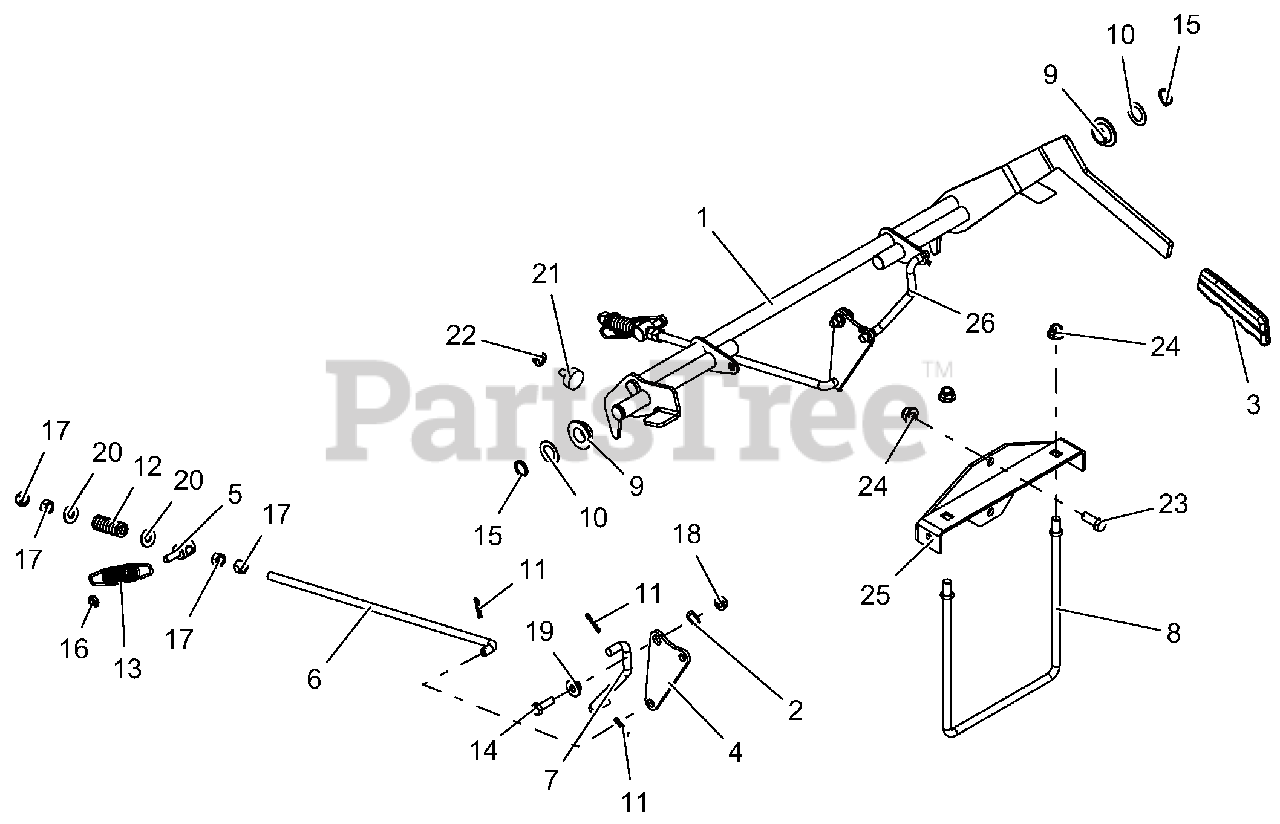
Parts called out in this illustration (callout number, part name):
1	WLDMT, PARKING BRAKE LEVER
2	WAVE WASHER .531X.781X.125 FH
3	GRIP, PARKING BRAKE (YELLOW)
4	PLATE, BRAKE PIVOT-BLACK
5	TRUNNION, .31-18
6	ROD, BRAKE ADJ.
7	LINKAGE, RH BRAKE ACTUATING
8	ROD, BRAKE MTG
9	BSHG, FLANGE .762 X 1.48 X .44 NYLON
10	WSHR-HDND-THRST
11	PIN-HAIR, ENDRIES #25 YWZC
12	SPRG, COMPRESSION
13	SPRG, TENSION .105 X .850 X 4.880
14	BLT-HEX .31-18X1.00 GR5 YWZC
15	RG-RTNG-EXT .750x.078
16	@NUT-LK-CTR-JAM .31-18 YWZC
17	NUT-HEX .38-16 YWZC
18	NUT, LK-TOP-FLG .312-18 YWZC
19	BSHG, FLG .32X.500.344X.880
20	WSHR-FL-STL.38X.875X.083 YWZC
21	BUMPER, RUBBER
22	@NUT-SPNLK-FLG .312-18 YWZC
23	BLT-HEX .38-16X1.00 GR5 YWZC
24	NUT-LK-NYL-FLG .38-16 YWZC
25	WMT, SPRING ANCHOR BRKT-BLACK
26	LINKAGE, LH BRAKE ACTUATING
